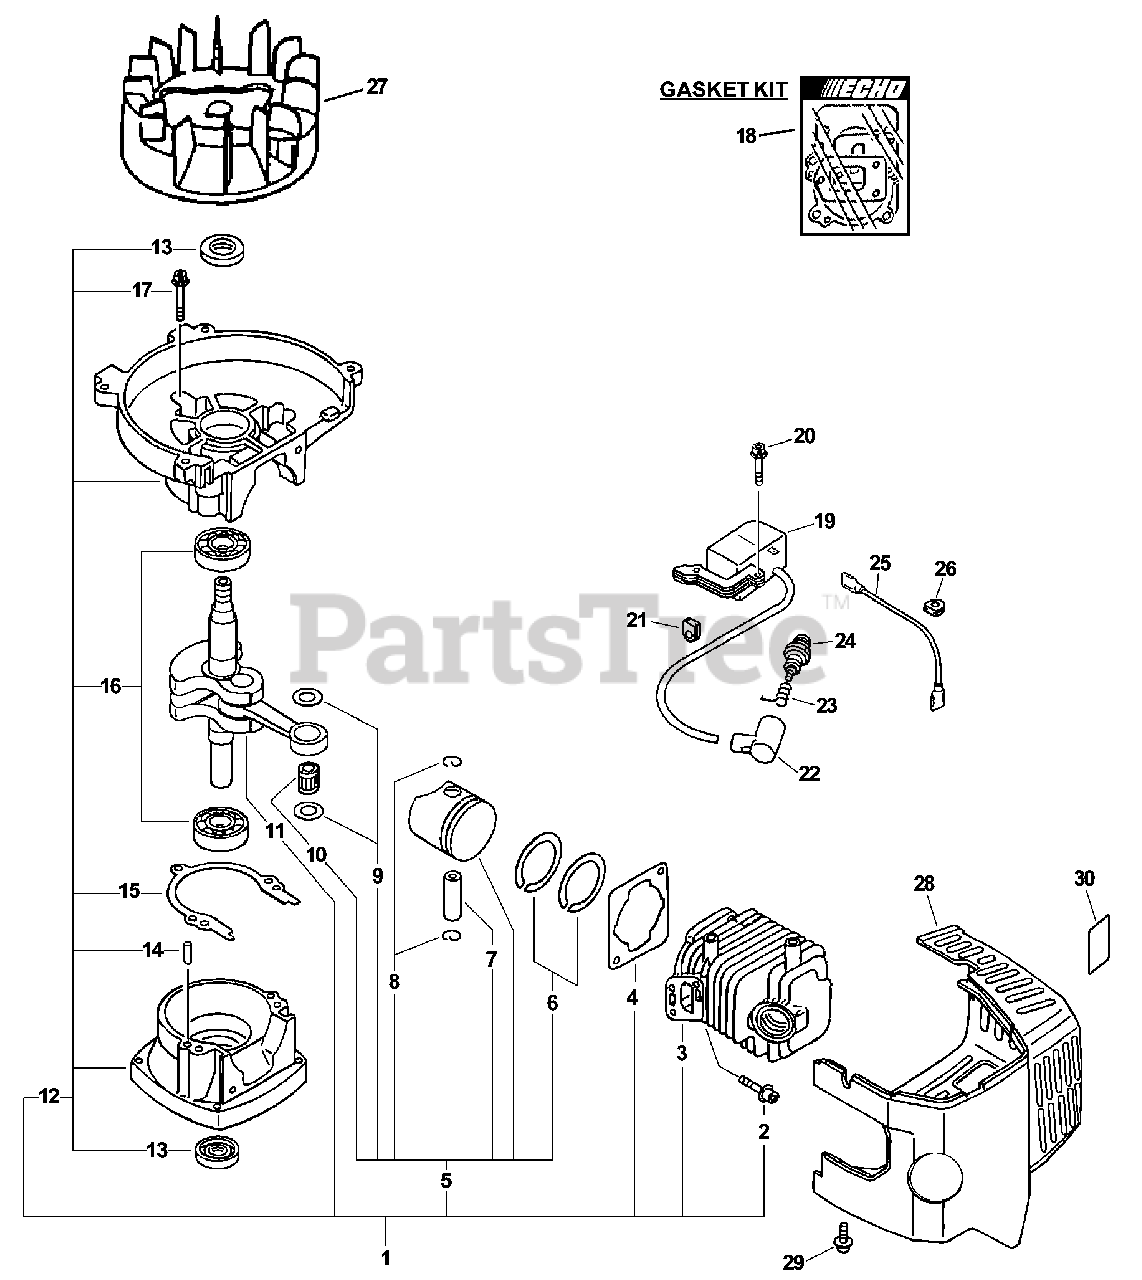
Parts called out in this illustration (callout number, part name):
1	SHORT BLOCK -- SB1050
2	SCREW - 5X22
3	CYLINDER
4	GASKET, CYLINDER
5	PISTON KIT
6	RING, PISTON
7	PIN, PISTON
8	RING, RETAINING
10	BEARING, NEEDLE - 8
11	CRANKSHAFT ASSY
12	CRANKCASE KIT
13	SEAL, OIL
14	PIN - LOCATING
15	GASKET, CRANKCASE
16	BEARING, BALL - 6201
17	SCREW - 5X28
18	GASKET KIT
19	COIL, IGNITION
20	SCREW - 4X22
22	CAP, SPARK PLUG
23	TERMINAL, SPARK PLUG CAP
24	SPARK PLUG -- BPM-7Y
25	LEAD - IGNITION
27	FLYWHEEL
28	COVER, ENGINE
29	SCREW - 4X20
30	LABEL - HOT SURFACE
